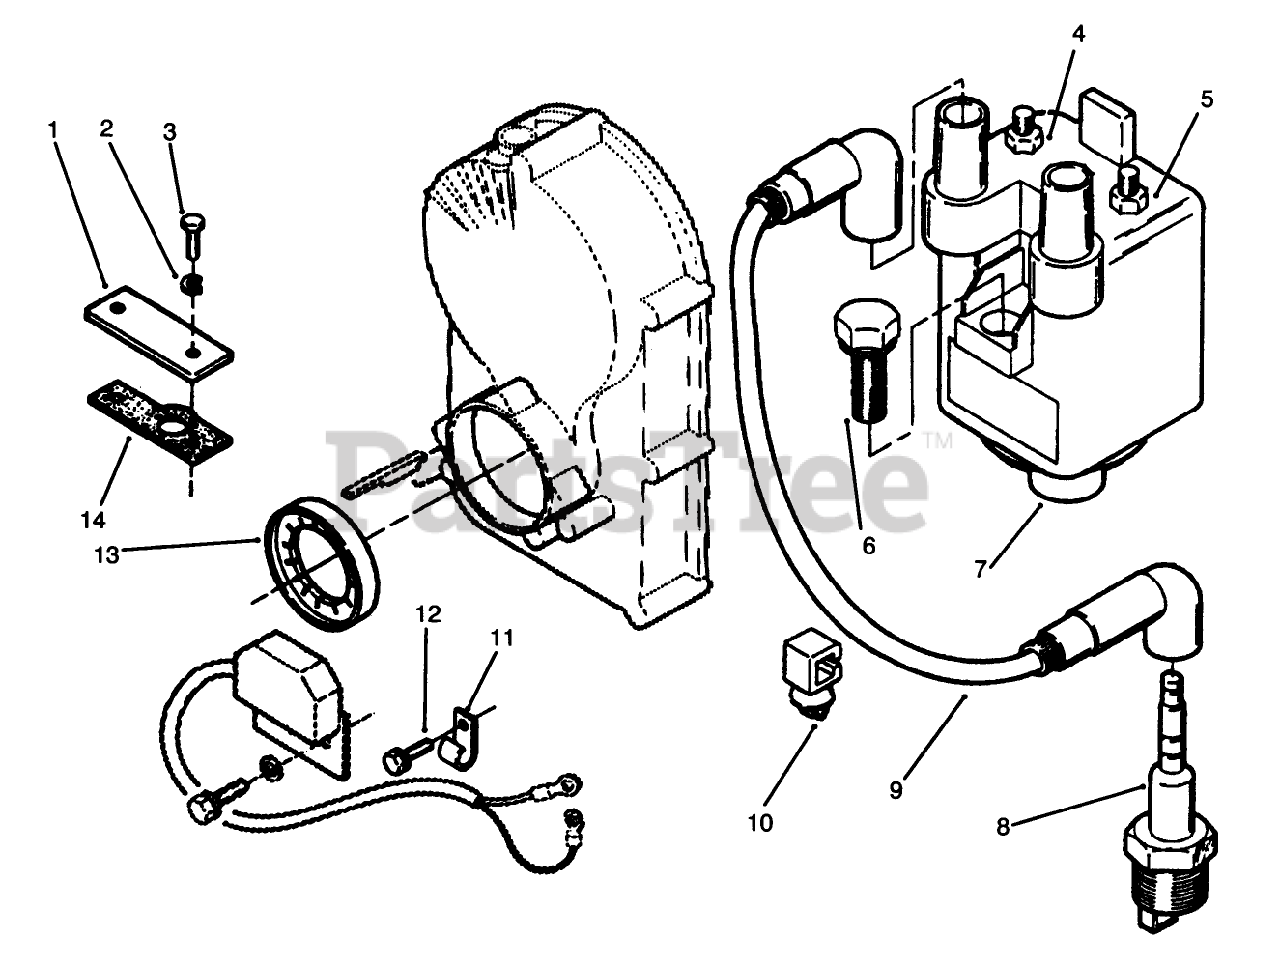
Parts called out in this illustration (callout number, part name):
1	PLATE-COVER
2	WASHER-FLAT
3	SCREW - CAP HEX HEAD
4	Nut
5	Nut
6	HEX-HEAD CAP SCREW
7	Coil-Battery Ignition (Incl. Ref. #4-5)
8	SPARK PLUG
9	Wire-Plug
10	WIRE ROUTING CLIP
11	Clip
12	SCREW-HH
13	ROTOR-IGNITION
14	Gasket-Plate
